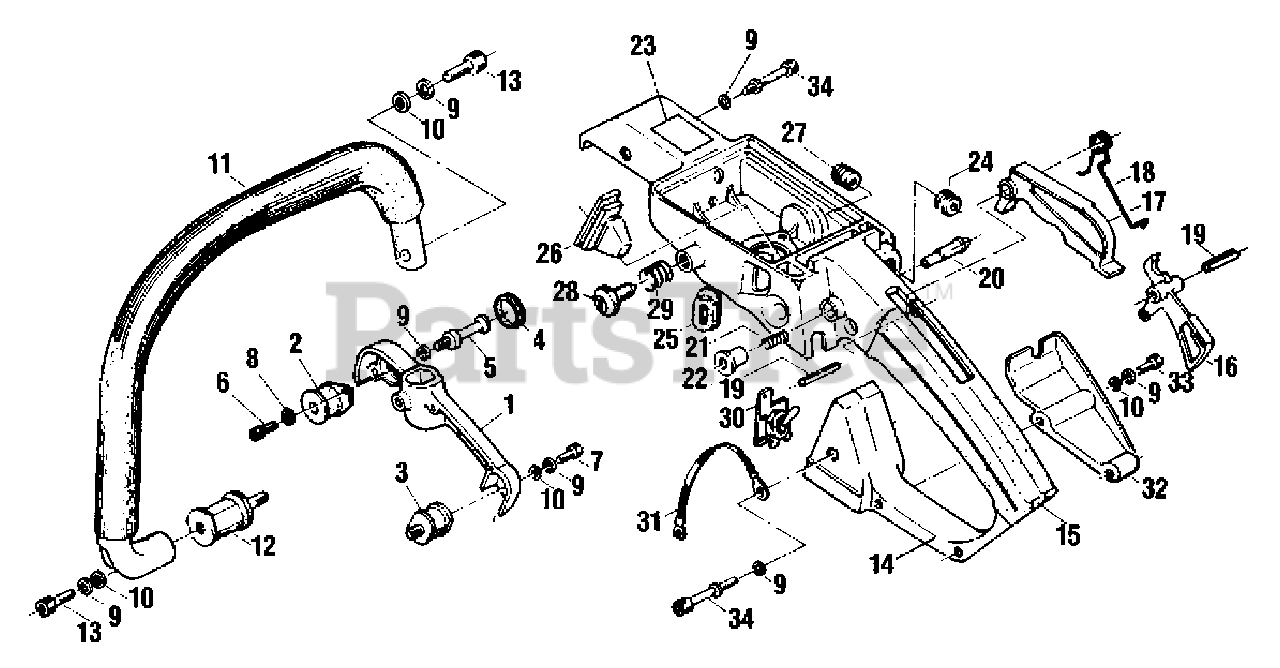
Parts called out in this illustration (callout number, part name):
1	BRACKET
2	CUSHION - 22
3	CUSHION - 18A
4	PLUG, BRACKET
5	BOLT, BRACKET
6	SCREW - 4X10
7	SCREW - 5X12
8	LOCKWASHER - 4
9	LOCKWASHER
10	WASHER - 5
11	HANDLE - FRONT
12	CUSHION - 18
13	SCREW - 5X25
14	HANDLE - REAR
15	GRIP, HANDLE
16	TRIGGER, THROTTLE
17	LEVER, LOCK
19	PIN - SPRING
20	STOPPER
22	KNOB, STOPPER
23	LABEL - CAUTION
27	GROMMET
28	SCREW, ADJUST
29	SPRING, ADJUST
30	IGNITION SWITCH ASSY
31	LEAD - GROUND
32	GUARD - REAR
33	SCREW - 5X18
34	BOLT
